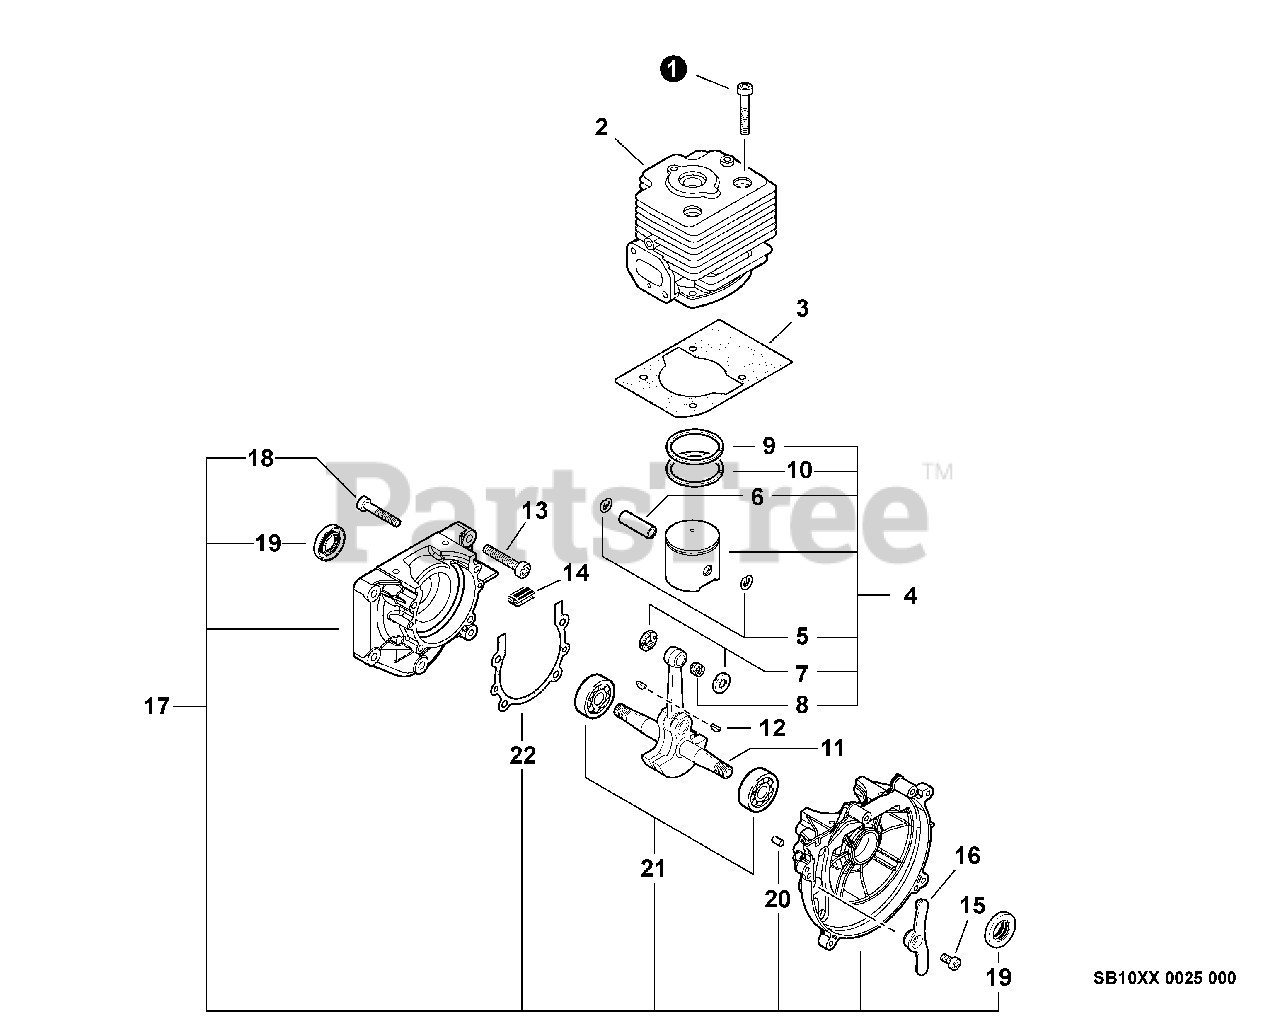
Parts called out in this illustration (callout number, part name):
1	SCREW - 5X25
2	CYLINDER
3	GASKET, CYLINDER
4	PISTON KIT
5	RING, RETAINING - 8
6	PIN, PISTON
7	WASHER - 10
8	BEARING, NEEDLE - 10
9	RING, PISTON
10	RING, PISTON
11	CRANKSHAFT ASSY
12	KEY - 3X14
13	SCREW - 6X30
14	COVER, DUST
15	SCREW - 5X10
16	COVER, DUST
17	CRANKCASE KIT
18	SCREW - 5X30
19	SEAL, OIL
20	PIN - LOCATING
21	BEARING, BALL - 6302
22	GASKET, CRANKCASE
